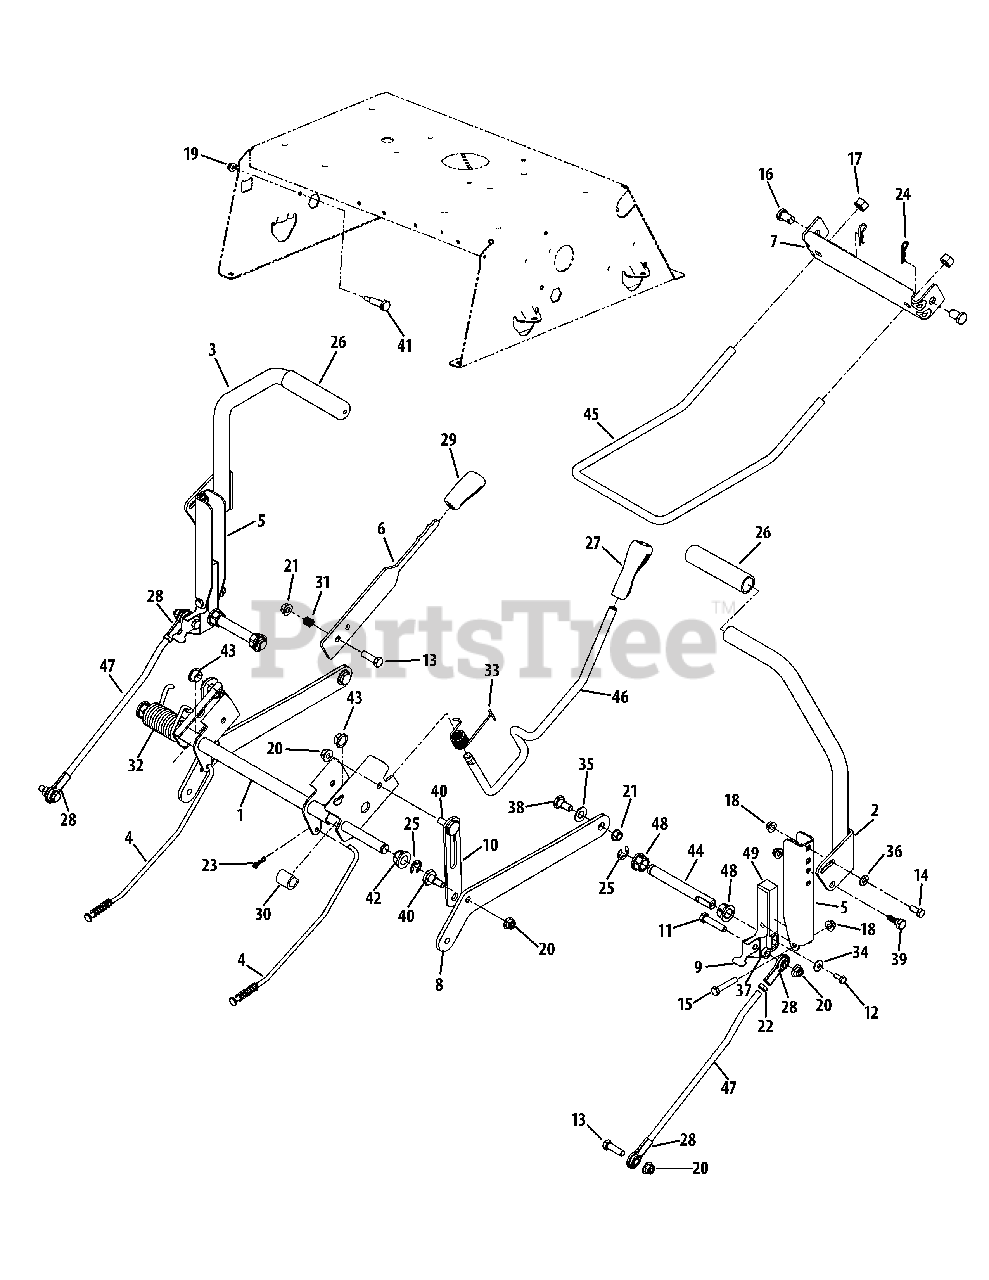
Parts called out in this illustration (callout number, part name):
1	Deck Lift Shift Assembly
2	RH Lapbar Lever Assembly - Gray
2	RH Lapbar Lever Assembly - Black
3	LH Labpar Lever Assembly - Gray
3	LH Labpar Lever Assembly - Black
4	Brake Rod Assembly
5	Lapbar Pivot Bracket
6	Brake/Shabs Assembly
7	Front Deck Hanger Bracket - Black
7	Front Deck Hanger Bracket - Red
8	Deck Lift Arm Plate - Black
8	Deck Lift Arm Plate - Red
9	Switch Actuator Bracket
10	Lift Link Plate
11	Hex Screw, 3/8-16 x 1.75
12	Hex Screw, 1/4-20 x .625
13	Hex Screw, 3/8-16 x 1.25
14	Hex Screw, 5/16-18 x .75
15	Hex Screw, 5/16-18 x 1.75
16	Clevis Pin, .50 x .78
17	Flex Lock Nut, 1/2-13
18	Flange Lock Nut, 5/16-18
19	Flange Lock Nut, 1/4-20 (50" Deck)
20	Flange Lock Nut, 3/8-16
21	Hex Lock Nut, 3/8-16, Centerlock
22	Jam Nut, 3/8
23	Bow-Tie Cotter Pin
24	Cotter Pin, .080 x 1.5625
25	E-Ring
26	Lapbar Grip
27	Handle Grip, 1/2
28	Rod End
29	Selector Handle
30	Spacer, .621 x 1.00
31	Compression Spring, .50 x .50
32	Torsion Spring, 1.191 x 2.78
33	Torsion Spring
34	Bell Washer, .265 x .75 x .062
35	Flat Washer, .510 x 1.00 x .060
36	Flat Washer, .344 x .688 x .065
37	Spacer, .380 x .625 x .265
38	Shoulder Bolt, 3/8-16 x .496 x .336
39	Shoulder Screw, 5/16 x .437 x .268
40	Shoulder Screw, .500 x .434
41	Shoulder Screw, .374 x 1.16 (50" Deck)
42	Hex Flange Bearing
43	Flange Bearing, .626 x .938 x .344
44	Shaft Control
45	Front Hanger Deck Lift Rod
46	Deck Lift Handle Rod
47	Lapbar Control Rod
48	Hex Flange Bearing, .629
49	Control Hub
